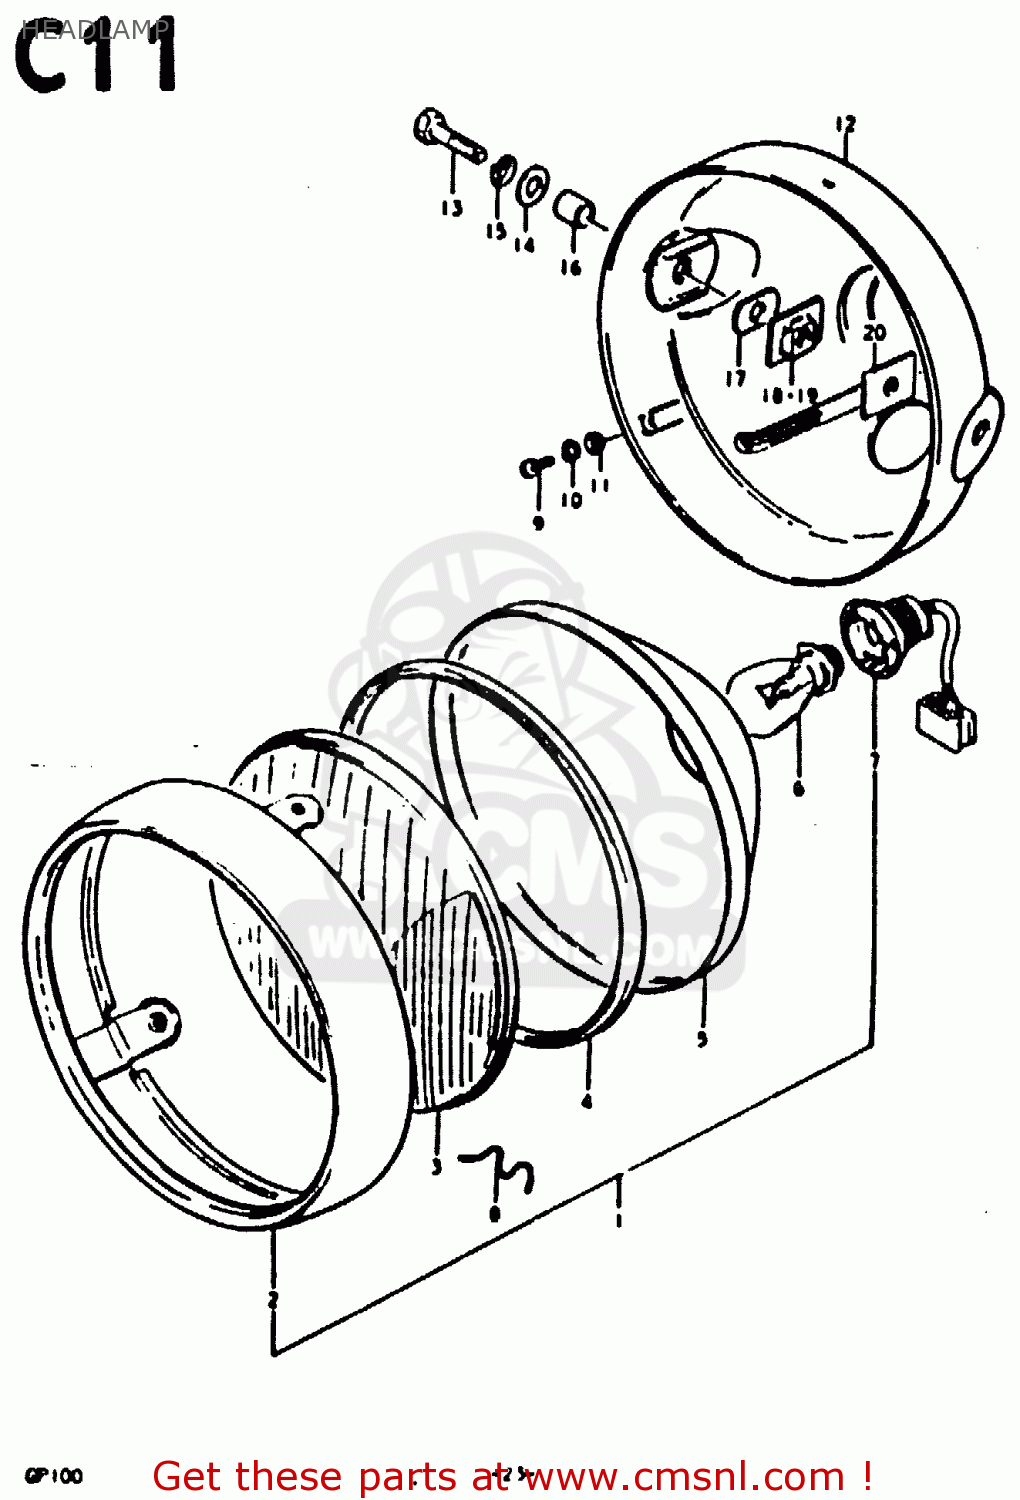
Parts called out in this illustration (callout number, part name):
1	HEADLAMP ASSY
2	RIM
3	LENS
4	GASKET (NAS)
5	REFLECTOR,HEADLAMP
6	BULB(6V25/25W,STANLEY,A7007)
7	SOCKET,HEADLAMP
8	SPRING
9	SCREW
10	LOCK WASHER
11	WASHER
12	HOUSING,HEADLAMP
13	BOLT
14	WASHER
15	LOCK WASHER
16	SPACER (8.8X12X7)
17	CUSHION
18	PLATE,HEADLAMP HOUSING
